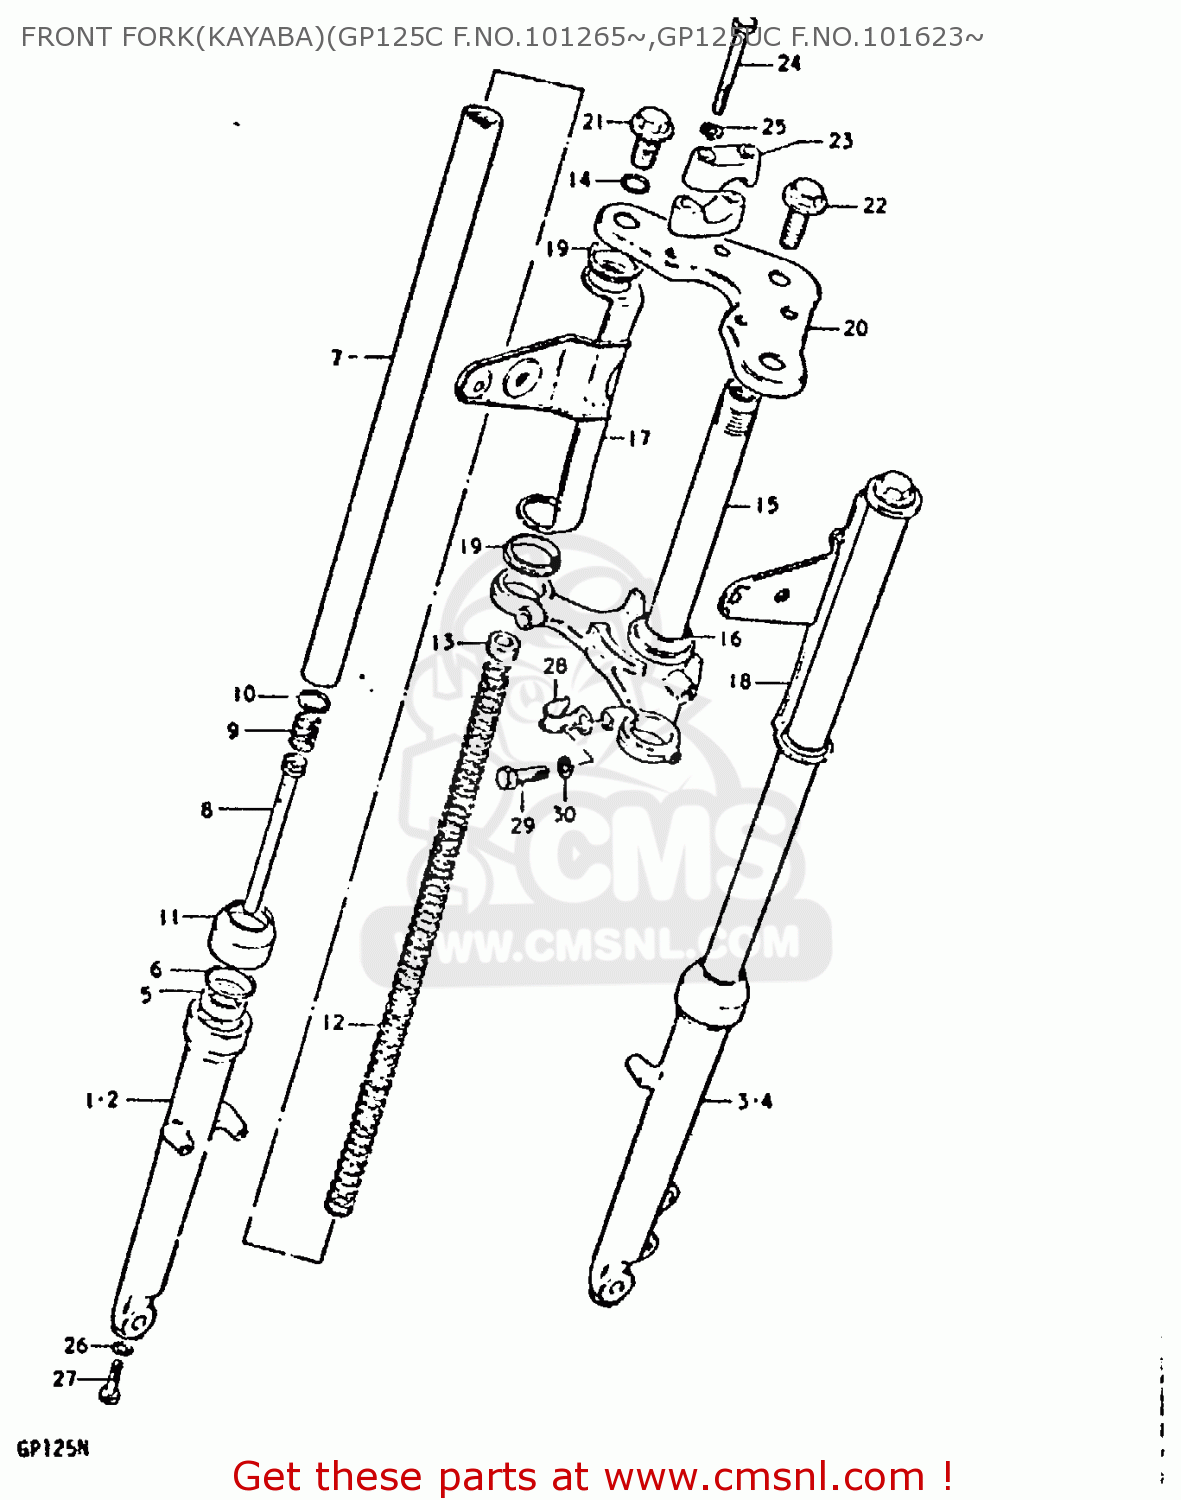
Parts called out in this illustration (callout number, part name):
1	OUTER TUBE, RH
3	OUTER TUBE, LH
5	SEAL,OIL
6	RING,SNAP
7	TUBE, INNER
8	CYLINDER
9	SPRING
10	RING
11	DUST SEAL
12	SPRING
13	NUT
14	O-RING,FORK INNER TUBE
15	STEM, STEERING
16	RACE,STEERING OUTER LWR
17	BRACKET, HEADLAMP RH (BLACK)
18	BRACKET, HEADLAMP LH (BLACK)
19	GASKET (NAS)
20	HEAD, STEERING STEM (BLACK)
21	CAP
22	BOLT
23	HOLDER,HANDLE UPR
24	BOLT 8X55
25	LOCK WASHER
26	GASKET (NAS)
27	BOLT,FORK CYLINDER(10X25)
28	CLIP,SPEEDOMETER CABLE
29	BOLT 10X30
30	LOCK WASHER
